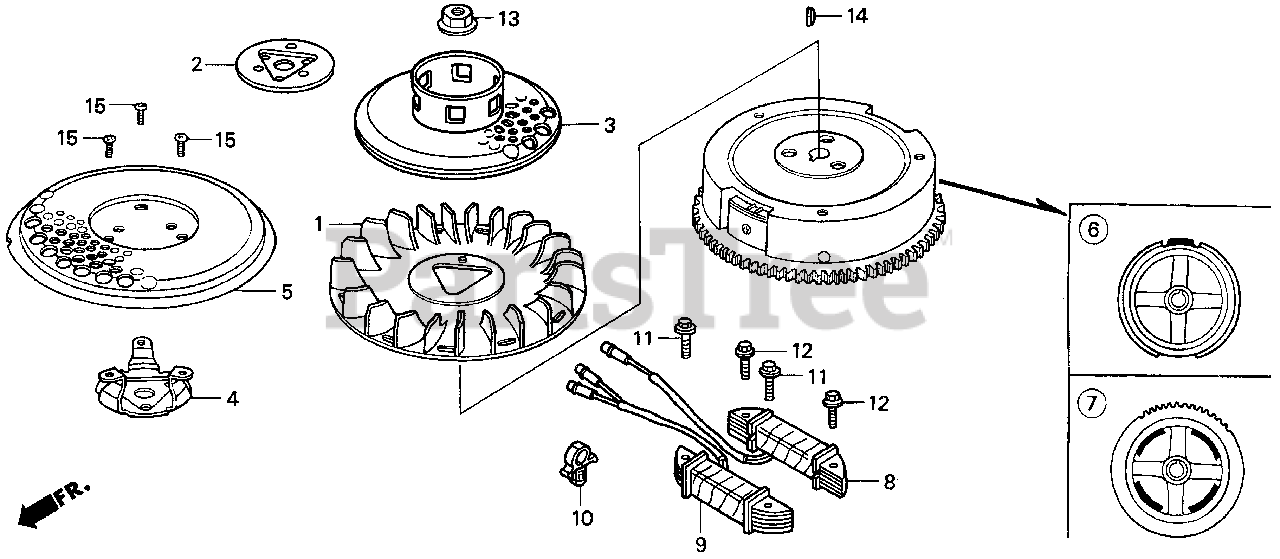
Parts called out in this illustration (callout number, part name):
1	FAN, COOLING
2	PLATE, COOLING FAN SETTING
6	FLYWHEEL COMP.
8	COIL ASSY., CHARGE
10	CLIP, BRAKE PIPE (A)
12	BOLT, FLANGE (6X28)
13	NUT, SPECIAL (16MM) (1)
14	KEY, SPECIAL WOODRUFF (25X18)
